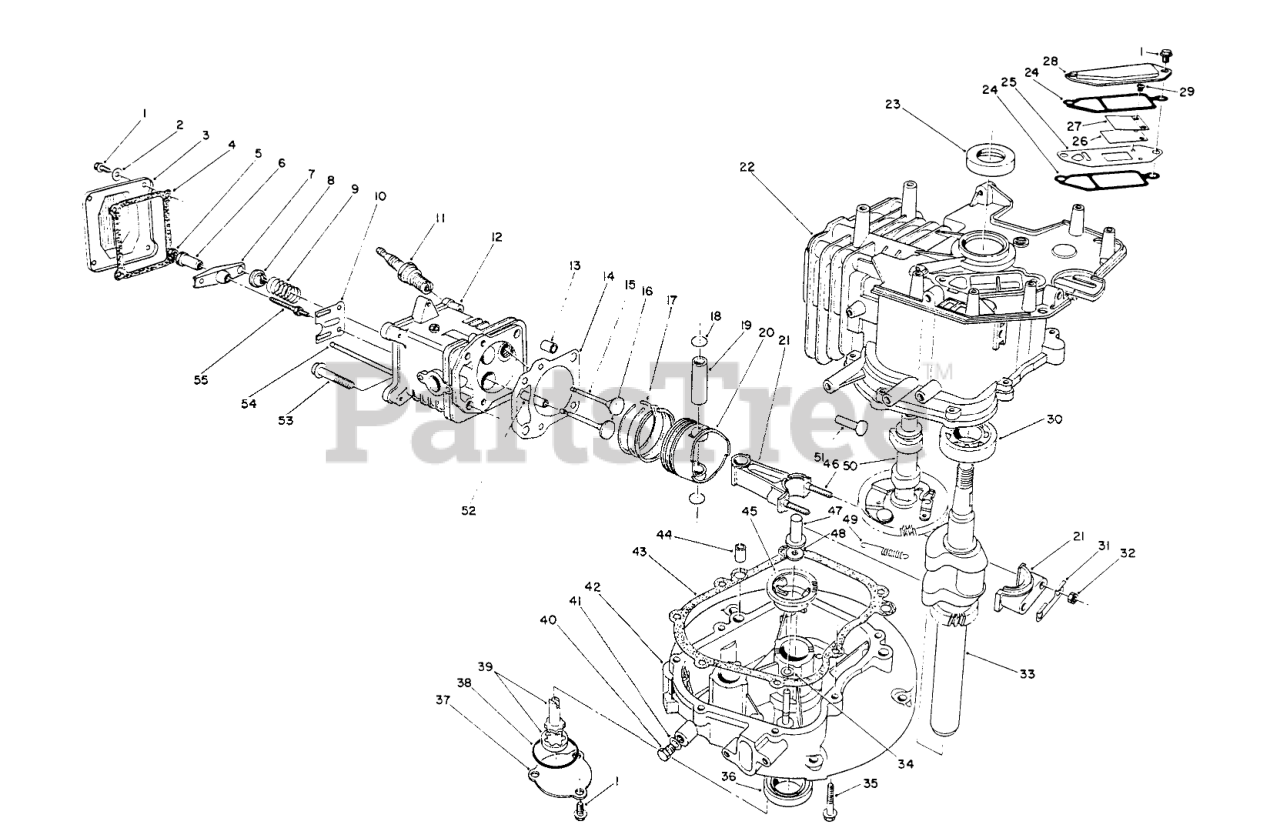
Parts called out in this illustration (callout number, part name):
2	WASHER
3	COVER
4	GASKET
6	PIVOT
8	RETAINER
9	SPRING
10	GUIDE
11	SPARK PLUG
12	Head-Cylinder (Incl. Ref. #52)
14	GASKET
15	VALVE-EXHAUST
16	VALVE-INTAKE
17	RING SET
18	CIRCLIP
20	PISTON
21	Connecting Rod Assembly (Incl. Ref. #31, 32 & 46)
22	Block-Engine (Incl. Ref. #23 & 30)
24	GASKET
25	Plate-Breather
26	Valve-Reed
27	Retainer-Reed Valve
28	COVER
29	Screw-Reed Valve
30	BEARING
31	Plate-Lock
33	CRANKSHAFT
34	WASHER
37	COVER
38	O-RING
39	OIL PUMP
40	OIL DRAIN PLUG
41	GASKET
42	Crankcase
43	GASKET
45	GOVERNOR FLYWEIGHT ASM
47	PLUNGER
48	WASHER
49	SPRING
50	Camshaft Assembly (Incl. Ref. #49)
51	TAPPET
52	GUIDE
